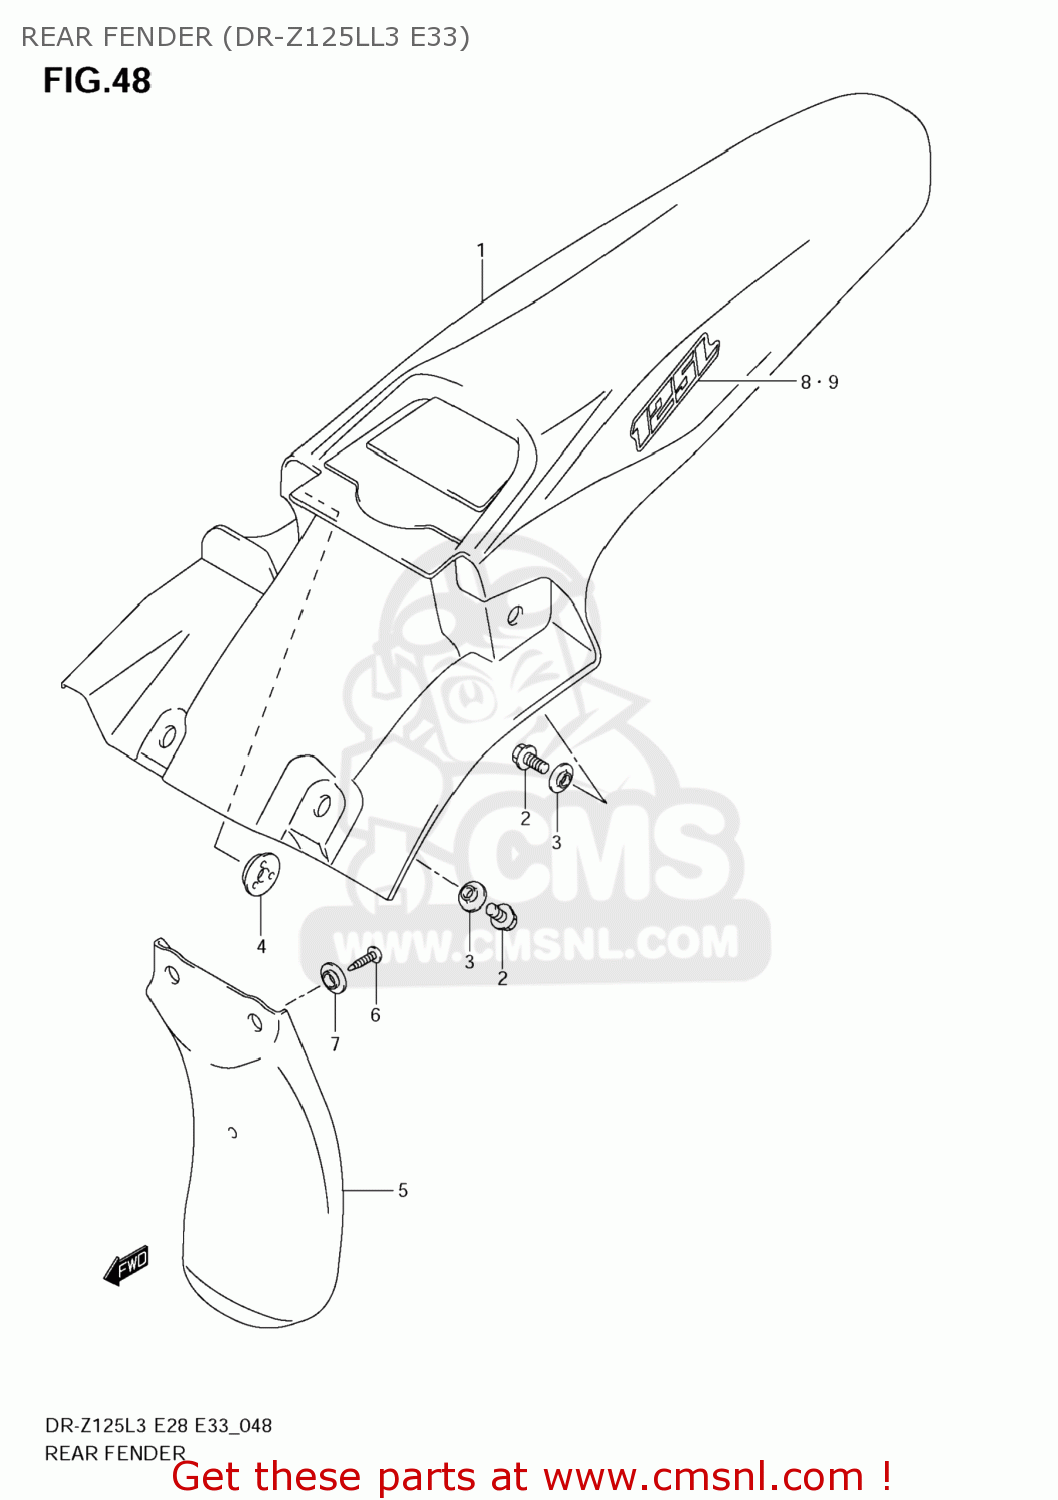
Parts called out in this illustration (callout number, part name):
1	FENDER,RR
2	BOLT(6X16)
3	WASHER
4	WASHER
5	MUDGUARD,RR FENDER FR
6	SCREW(5X16)
7	WASHER
8	EMBLEM,125L,R
9	EMBLEM,125L,L
